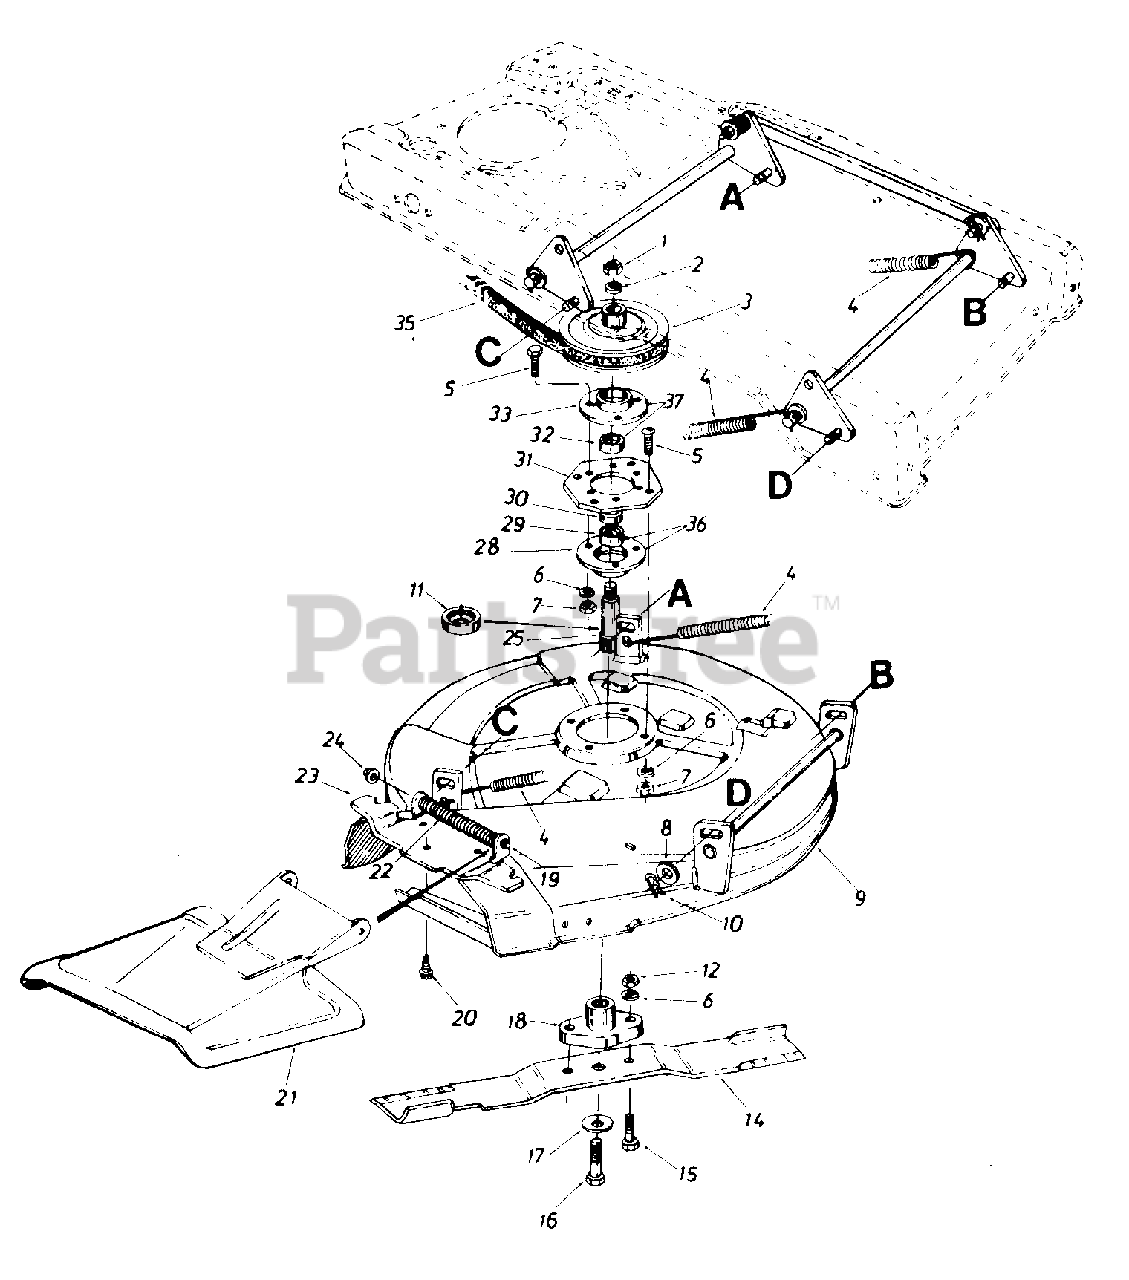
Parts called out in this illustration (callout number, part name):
1	Hex Jam Nut 5/16-18 Thd.
2	Bell-Wash. .630" I.D. x 1.25" O.D.
3	5/8" "V"-Pulley .75" I.D. x 9.5"
4	Extension Spring .56" O.D. x 1 0.5
5	Hex Bolt 5/16-18 x .75" Lg.
6	L-Wash. 5/16" I.D.
7	Hex Nut 5/16-18 Thd.
8	Fl-Wash. .510" I.D. x 1.0" O.D.
9	26" Deck Ass'y.
10	Inter. Cotter Pin 1/2" Dia.
11	Bearing Shield
12	Hex Nut 5/16-24 Thd.
14	Blade 26"
15	Hex Bolt Special 5/16-24 x 1.0" Lg.
16	Hex Bolt 3/8-24 x 1.00" Lg.
17	Bell-Wash. .391" I.D. x 1.38" O.D.
18	Blade Adapter
19	Hinge Pin
20	Hex Wash. Hd. TT-Scr. 1/4-20
21	Chute Cover Ass'y.
22	Torsion Spring
23	Adapter Plate
24	Cap Speed Nut 1/4" Rod
25	Blade Spindle 4.42" Lg.
28	Bearing Housing 1.85
29	Ball Brg. .787" I.D. x 1.85" O.D.
30	Spacer 1.0" O.D. x .790" I.D. x.350" Lg.
31	Spindle Mounting Plate
32	Ball Brg. .787" I.D. x 1.85" O.D.
33	Open Brg. Housing 1.85
35	"V"-Belt
36	Brg. Hsg. Ass'y.
37	Brg. Hsg. Ass'y.
